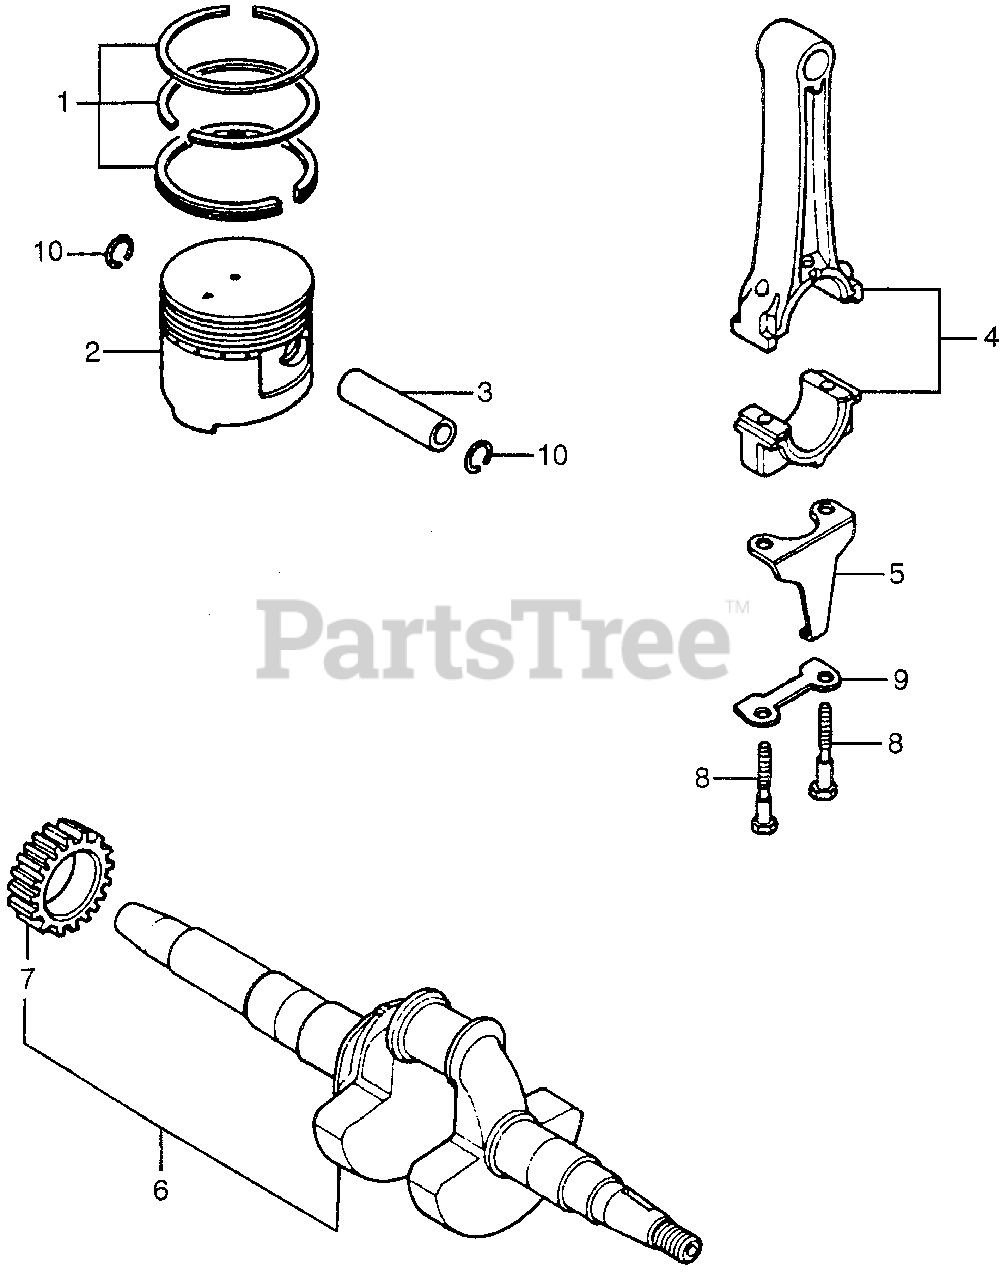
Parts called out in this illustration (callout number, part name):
1	RING SET, PISTON (STD)
1	RING SET, PISTON (OS 0.25)
1	RING SET, PISTON (OS 0.50)
1	RING SET, PISTON (0.75)
2	PISTON (STD)
2	PISTON (OS 0.25)
2	PISTON (OS 0.50)
2	PISTON (0.75)
3	PIN, PISTON
4	ROD ASSY., CONNECTING
4	ROD ASSY., CONNECTING (US 0.25)
5	DIPPER, CONNECTING ROD (NOT AVAILABLE)
6	CRANKSHAFT (V-TYPE)
7	GEAR, TIMING
8	BOLT, CONNECTING ROD (6MM)
9	WASHER B, CONNECTING ROD
10	CLIP, PISTON PIN (15MM)
